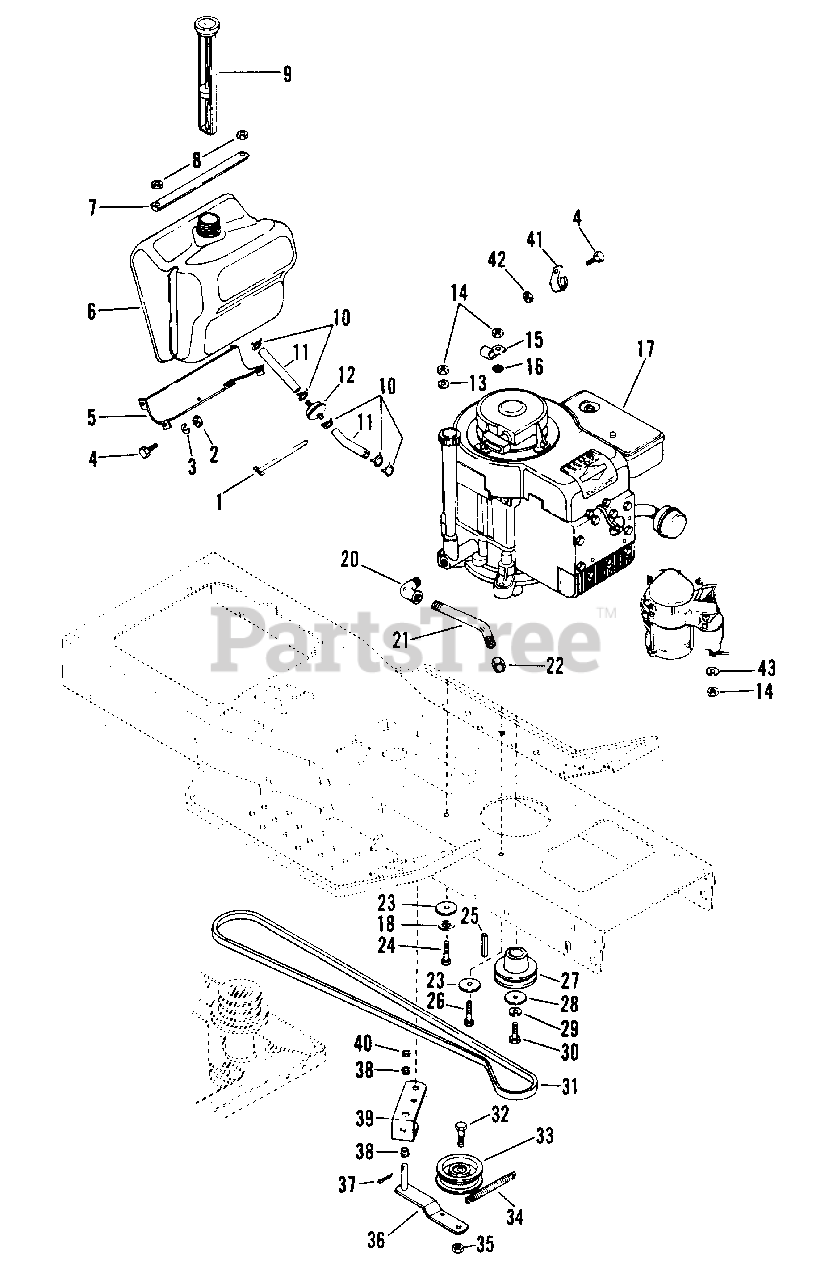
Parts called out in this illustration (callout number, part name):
1	TIE DOWN
2	NUT, HEX 1/4-20
3	WASHER, LOCK 1/4 REG.
4	BOLT, HEX 1/4-20X.50
5	SUPPORT, LOWER TANK
6	TANK, FUEL
7	STRAP, CLAMP
8	NUT, LOCK 1/4-20
9	GAUGE, FUEL
10	CLAMP, HOSE
11	LINE, FUEL
12	FILTER, FUEL
13	WASHER, FLAT .312X.734X.065
13	WASHER, LOCK 5/16 SP
14	NUT, LOCK 5/16-18
14	NUT, HEX M8-1.25
15	CLIP
16	WASHER, LOCK 5/16 EXT. TOOTH TYA
17	ENGINE, 12 HP B&S
17	ENGINE, 12.5 KAWASAKI
18	WASHER, LOCK 5/16 SP
19	SCREW, CAP 5/16-18X.75
20	ELBOW, DRAIN
20	FITTING, 90 DEGREE SPECIAL
21	PIPE, OIL DRAIN
22	CAP, PIPE
22	CAP, HEX
23	WASHER, FLAT .312X1.625X.134
24	BOLT HEX 5/16-18X1.50
24	BOLT, HEX M8X1.25X40MM
25	KEY, SQUARE .25X2.0
26	BOLT, HEX 5/16-18X1.75
26	BOLT, HEX M8X1.25X25MM
27	PULLEY, ENGINE
27	SHEAVE, ENGINE
28	WASHER, FLAT .563X1.375X.109
29	WASHER, LOCK 7/16 SP HEAVY
30	BOLT, HEX 7/16-20X1.00
30	SCREW, CAP M10X1.5X28
31	V-BELT
32	BOLT, HEX 3/8-16X1.50
33	IDLER
34	SPRING
35	NUT, LOCK 3/8-16
36	ARM, IDLER
37	PIN, COTTER .125X1.00
38	BUSHING, FLANGE
39	PIVOT, IDLER
40	WASHER, FLAT .406X.812X.065
41	CLIP
42	NUT, LOCK 1/4-20
43	WASHER, LOCK 5/16 REG.
